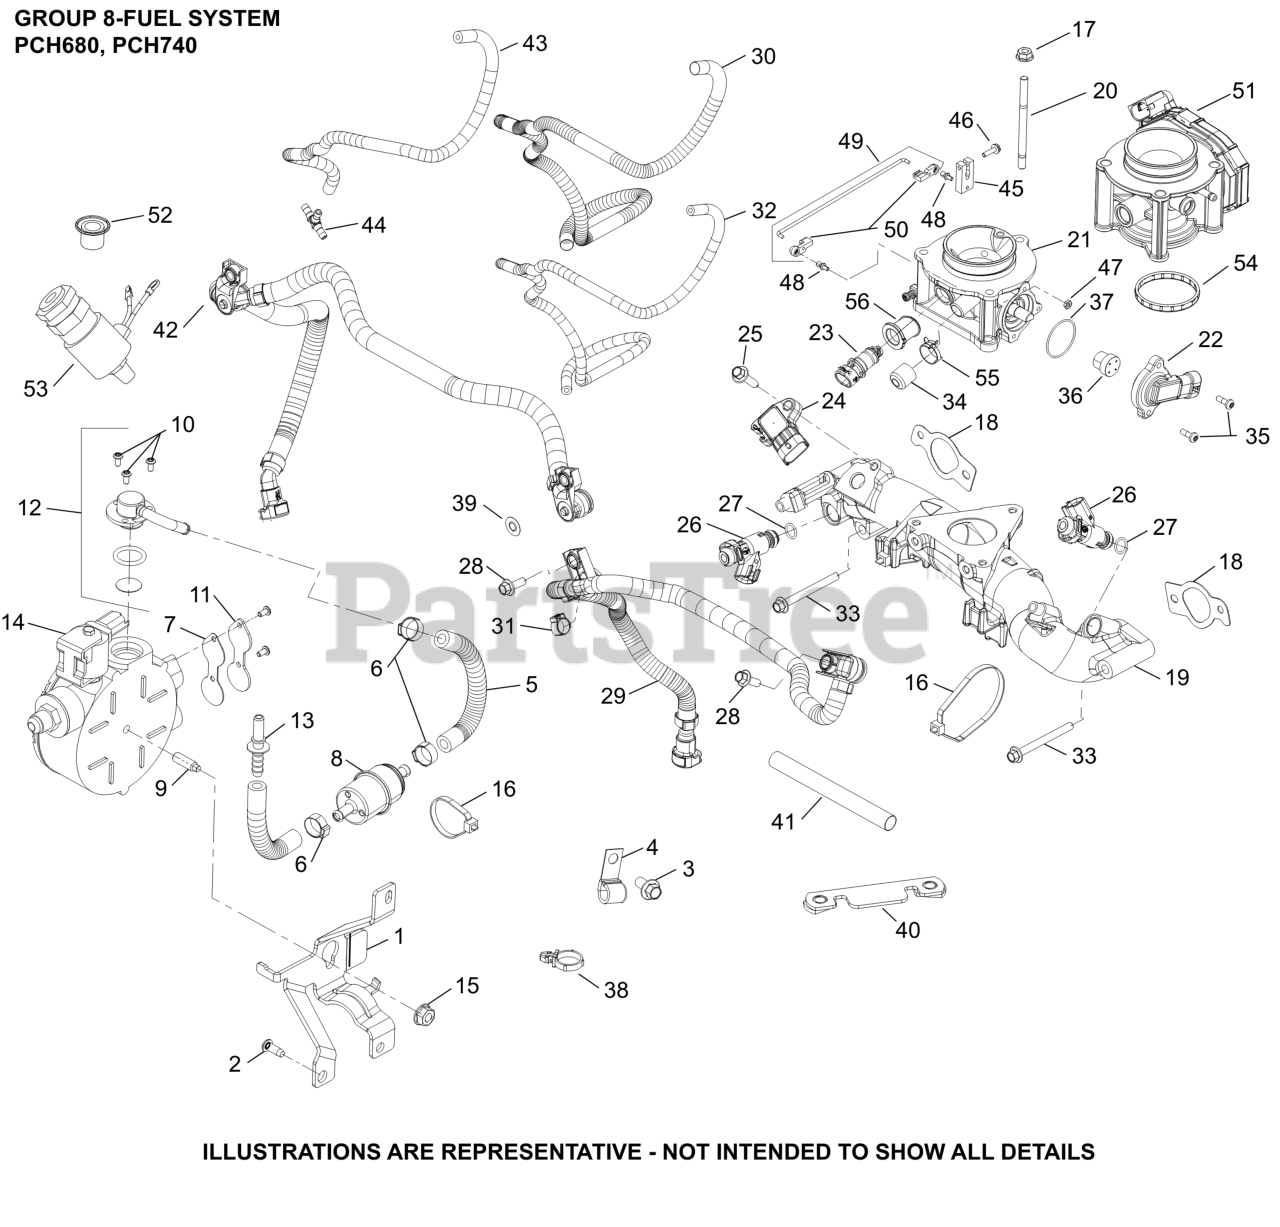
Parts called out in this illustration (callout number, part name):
1	BRACKET, LP REGULATOR
2	SCREW, THREAD FORMING
3	SCREW, FLG 8X1.25X16
5	HOSE, FUEL LOW PROPANE
6	CLAMP, HOSE
8	PROPANE FUEL FILTER-(#2505050S)
9	STUD, LP REGULATOR
10	SCREW, STARTER SWITCH
11	COVER, OIL PORT
12	KIT, OUTLET FITTING W/O-RING LPG
12	KIT, PLUG W/O-RING LPG (A7-173)
13	FITTING, FUEL - STRAIGHT
14	REGULATOR, W/RTV
15	NUT, FLG M8X1.25
19	KIT, MANIFOLD
20	STUD,M6X1.0X84
21	BODY, THROTTLE ASM (30)
22	SENSOR, THROTTLE POSITION
24	SENSOR, T-MAP
26	INJECTOR, GASEOUS FUEL
27	KIT, FUEL INJECTOR O-RING
28	SCREW, FLG M6x1.0x20
29	FUEL HOSE ASSY(ECV,FCV,EZT,EKT,PCH,PCV)
30	SLEEVE, ANTI-ABRASION
30	SLEEVE, ANTI ABRASION
32	HOSE, EVAPORATIVE
33	SCREW, FLG M6X1.0X60
34	CAP, MASKING
36	MAGNET ASSEMBLY, TPS
37	O-RING, TPS SENSOR
39	CLIP, RETAINER
40	BRACKET, MOUNTING
54	O-RING, THROTTLE BODY
NI	RETAINER, WIRE HARNESS
NI	KIT, LOCK-OFF ASSY LPG (A7-175)
NI	KIT, VAPORIZER FILTER REPL'MT LPG(A7-170
